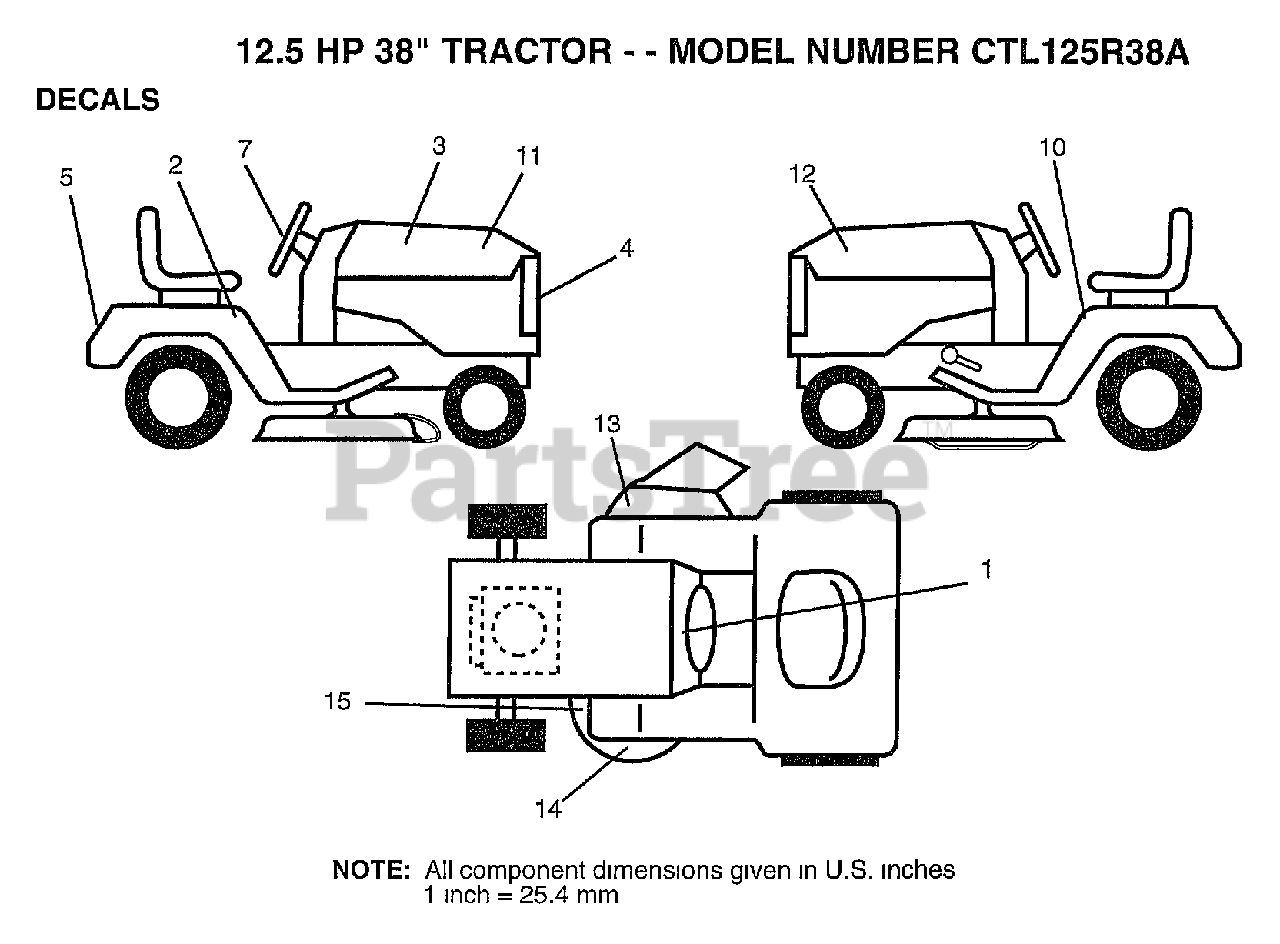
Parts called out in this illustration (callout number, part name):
1	DECAL.INST.OPER
2	DECAL.FEND.QUICKS
3	DECAL.HOOD.12.5
4	DECAL.GRILLE
5	DECAL.FENDER
7	DECAL.STG.WHL.INS
10	DECAL
11	DECAL.HOOD.RH
12	DECAL.HOOD.LH
13	"DECAL, WARNING"
15	DECAL
